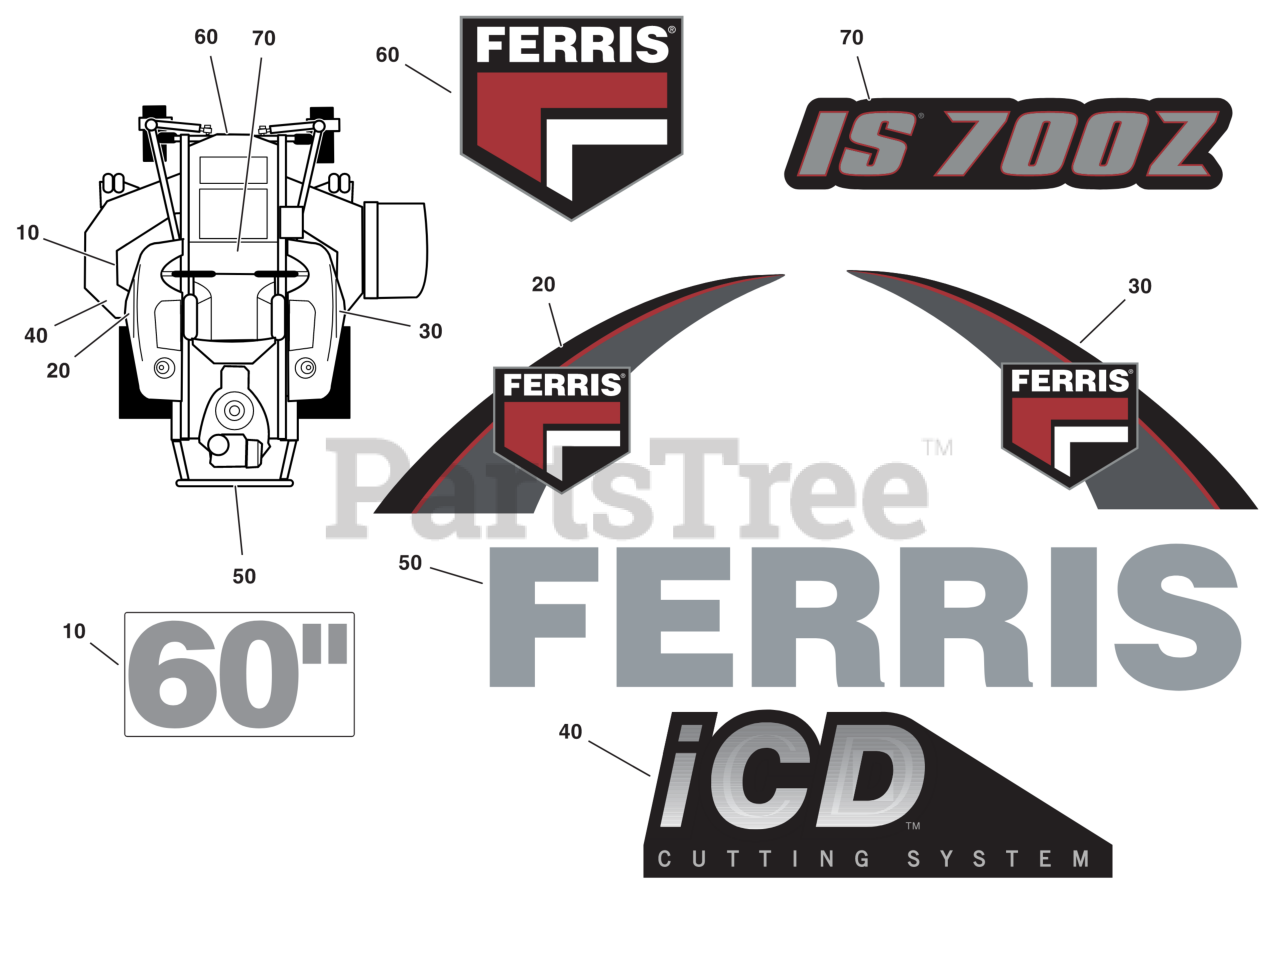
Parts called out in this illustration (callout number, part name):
10	DECAL, 60"
20	DECAL, MODEL, LEFT HAND
30	DECAL, MODEL, RIGHT HAND
40	DECAL, ICD CUTTING SY
50	DECAL, BRAND
60	DECAL, BRAND
70	DECAL, MODEL
